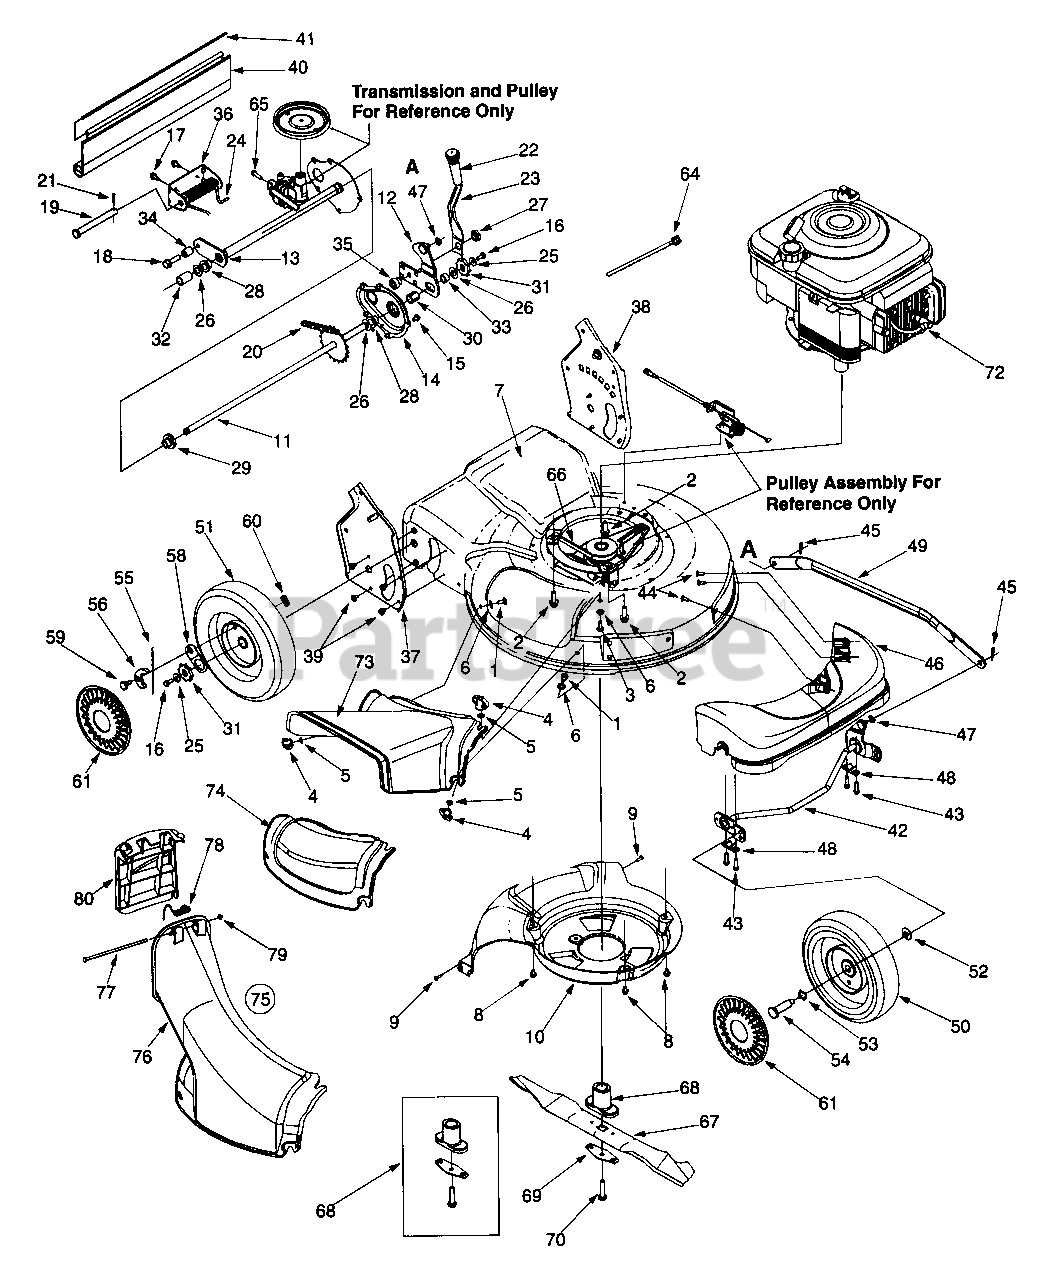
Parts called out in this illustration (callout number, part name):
1	Carriage Screw 1/4-20 x .62
2	Scr. TT: 3/8-18:1.00
3	Scr. 1/4-20 x .750
4	Wing Nut 1/4-20
5	Nut, Push .25 I.D. x .50 O.D.
6	Wash. Fl. .334 I.D. x .62 x .03
9	Scr. HL. 1/2-14 x .750
10	Baffle
11	Rear Axle Ass'y
16	Cap Screw HH 1/4-20 x .620
17	Scr. AB 1/4-14 x .625
18	Scr. 3/8 116 x .25
19	Clevis Pin .50 Dia. x 4.82 Lg.
20	Chain-Endls. #48 .500P x 24L
21	Cotter Pin .125 O.D. x .75
23	Spring Lever
24	Torsion Spring
25	Bell Wash. .285 x .75 x .082
26	Fl. Wash. .508 I.D. 1.000 x.020
27	Nut Shld. .825 Dia. x .165 Lg.
28	Hx.Flg. Brg. .506 I.D. x .590 L.
29	Hx.Flg. Brg. .506 I.D. x .715 L.
30	Hx. Slv. Brg. .504 I.D. x .830 L.
31	Wheel Rachet
32	Spa. .550 I.D. x /750 O.D.
33	Spa. .51 .D. x .70 O.D. x 38 L.
34	Spa. .385 x .624 x .700
35	Shld. Spa. .385 I.D. x .715 Lg.
40	Trail Shield
41	Trail Shield Wire
43	Hx Scr. Wash Hd. Hi.-Lo.
44	Scr. Torx, Truss Hi.-Lo.
45	Cotter Pin .072 x 1.12 Lg.
46	Fr. Axle Cover, Yellow
47	Bowed Washer
48	Bush. Block .505 Dia. x.62
50	Wheel 8 x 2 Link, Yellow
51	Wheel 9 x 2 Link Yellow, Slv.
52	Spr. Wash. .401 x .870 x .063
53	Wave Wash .510 x .750 x .017
54	Shldr Scr .498 x 1.445 x 3/8-16
55	Spring, Ratchet, Plastic
56	Pawl - R.H.
58	Ratchet Pawl Plate
59	Scr. Shld. .340 x .285
60	Top Lock Tab Weld Nut 1/4-20
61	Hubcap - Yellow
62	Screw .620 Hx. Slt. Wsh.
63	Casing Clamp, Throttle
64	Cable Tie
65	Hex Scr. 5/16-18
66	V-Belt
67	21" Mulching Blade
68	Blade Adapter Kit
69	Blade Bell Support
70	Hex Bolt 3/8-24 x 2.5" Lg.
72	Spark Plug Insulator
73	Side Discharge Chute
74	Mulch Cover
75	Rear Chute Ass'y w/Door
76	Discharge Chute
77	Pivot Rod
78	Torsion Spring
79	Push Cap
80	Chute Door
